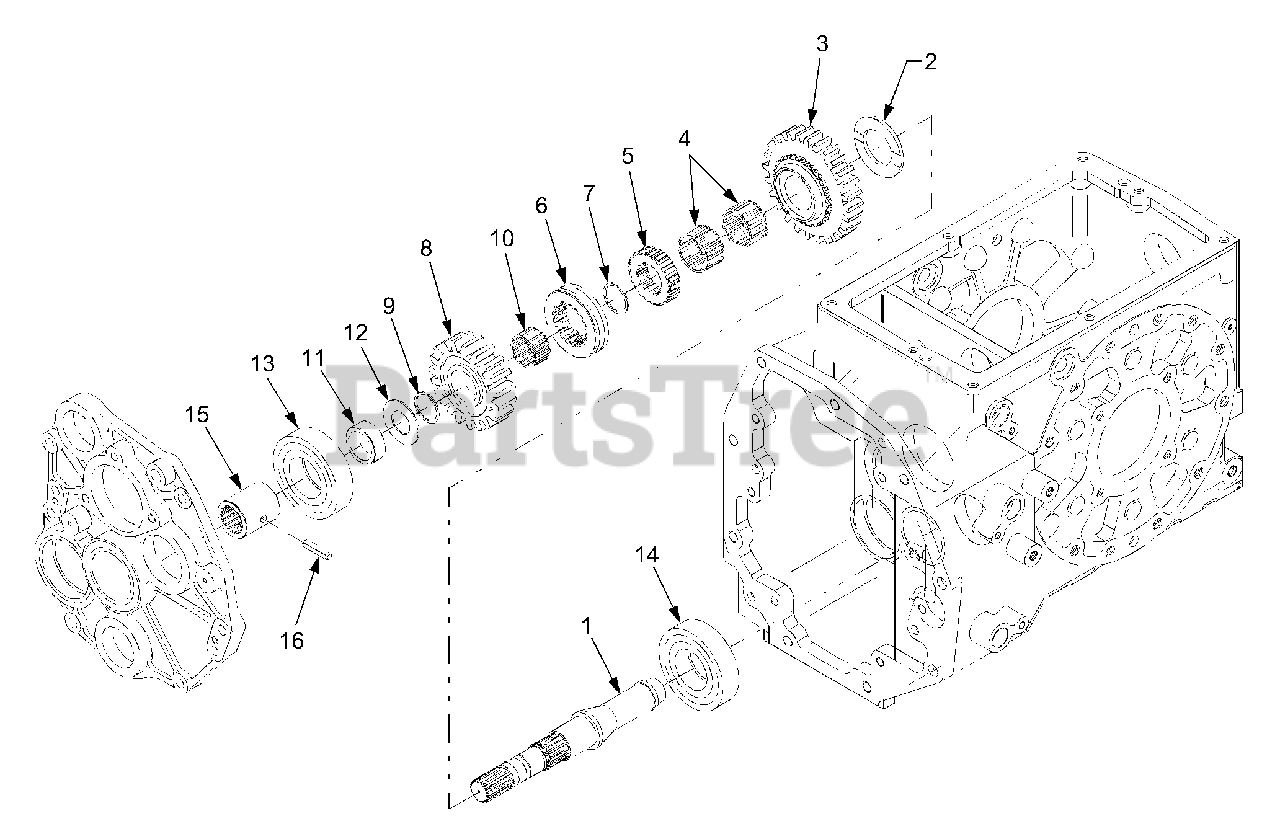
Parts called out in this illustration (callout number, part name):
2	Collar, Thrust
3	Gear, 32 Spur
4	Bearing, Needle
8	Gear, 18 Spur
10	Bearing, Needle
12	Collar, Thrust
13	Bearing, Ball
14	Bearing, Ball
